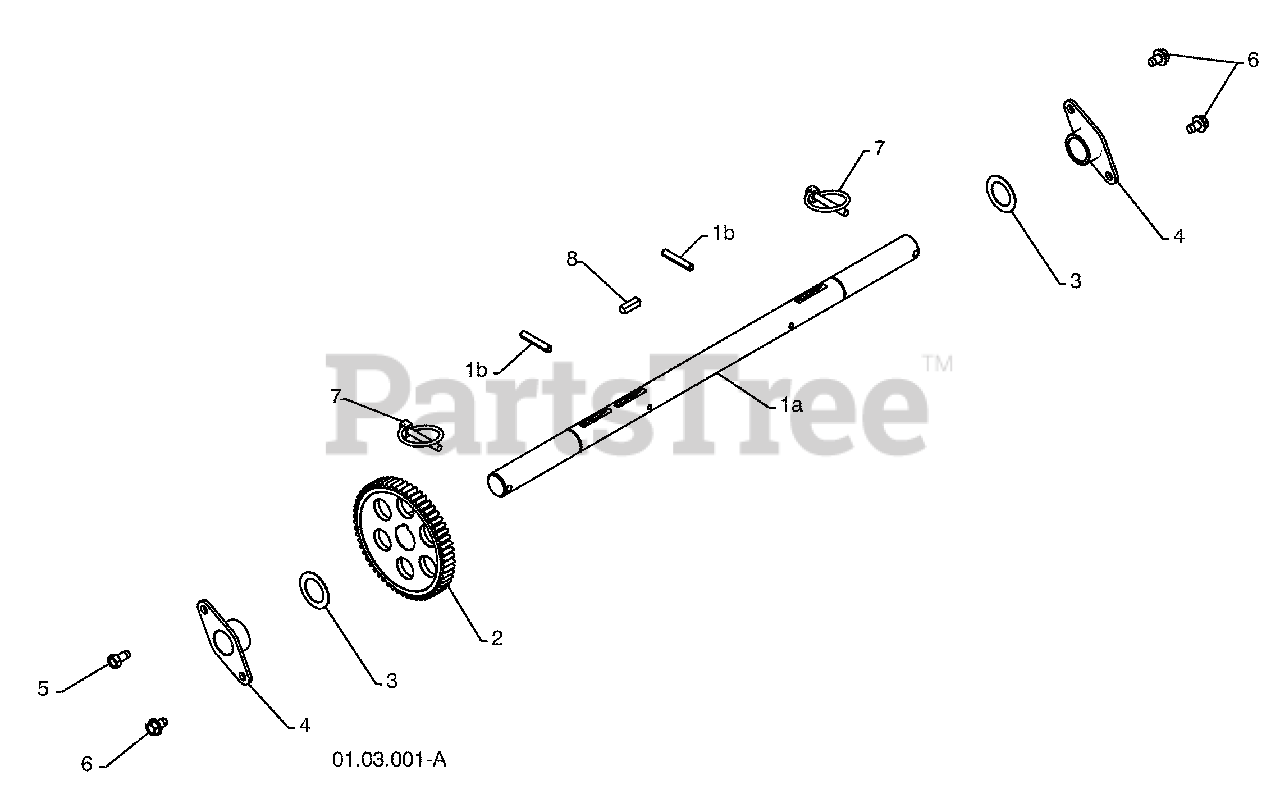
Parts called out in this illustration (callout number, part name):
1	AXLE ASSEMBLY
2	GEAR
3	THRUST WASHER
4	AXLE BEARING
5	SCREW 5/16-18 X .625
6	BOLT 5/16-18 X .500
8	SQUARE KEY
